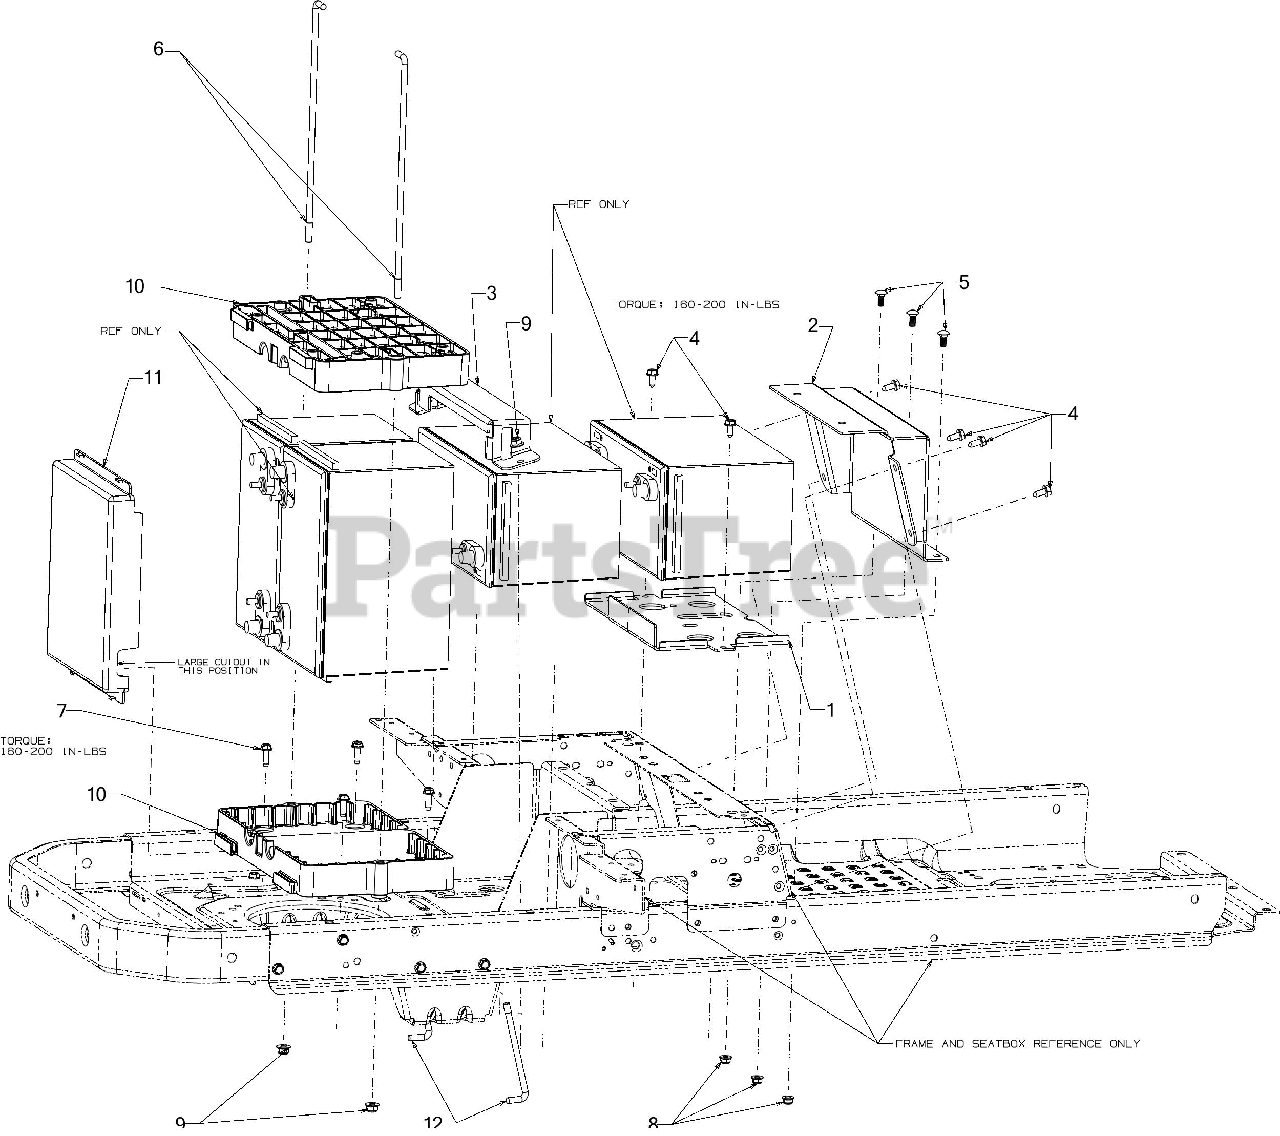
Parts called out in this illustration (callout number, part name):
1	FRONT BATTERY TRAY
2	FRONT BATTERY CLAMP
3	MIDDLE BATTERY CLAMP
4	SCREW 5/16-18 x .750
5	CARRIAGE BOLT 5/16-18 x .75
6	BOLT 3/8-16
7	SCREW 5/16-18 x 1.00
8	FLANGE LOCK NUT 5/16-18
10	REAR BATTERY TRAY
11	BATTERY TERMINAL COVER
12	BATTERY HOLD DOWN BOLT
